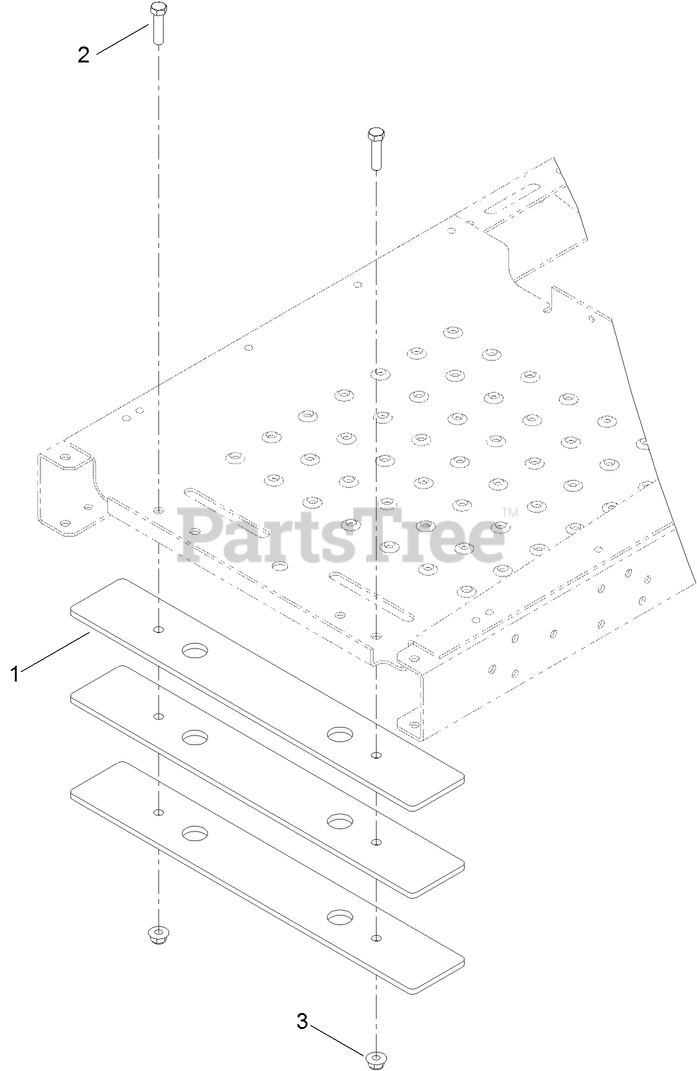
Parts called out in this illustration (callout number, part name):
1	PLATE-WEIGHT
2	SCREW-HH
3	NUT-HF, NI
